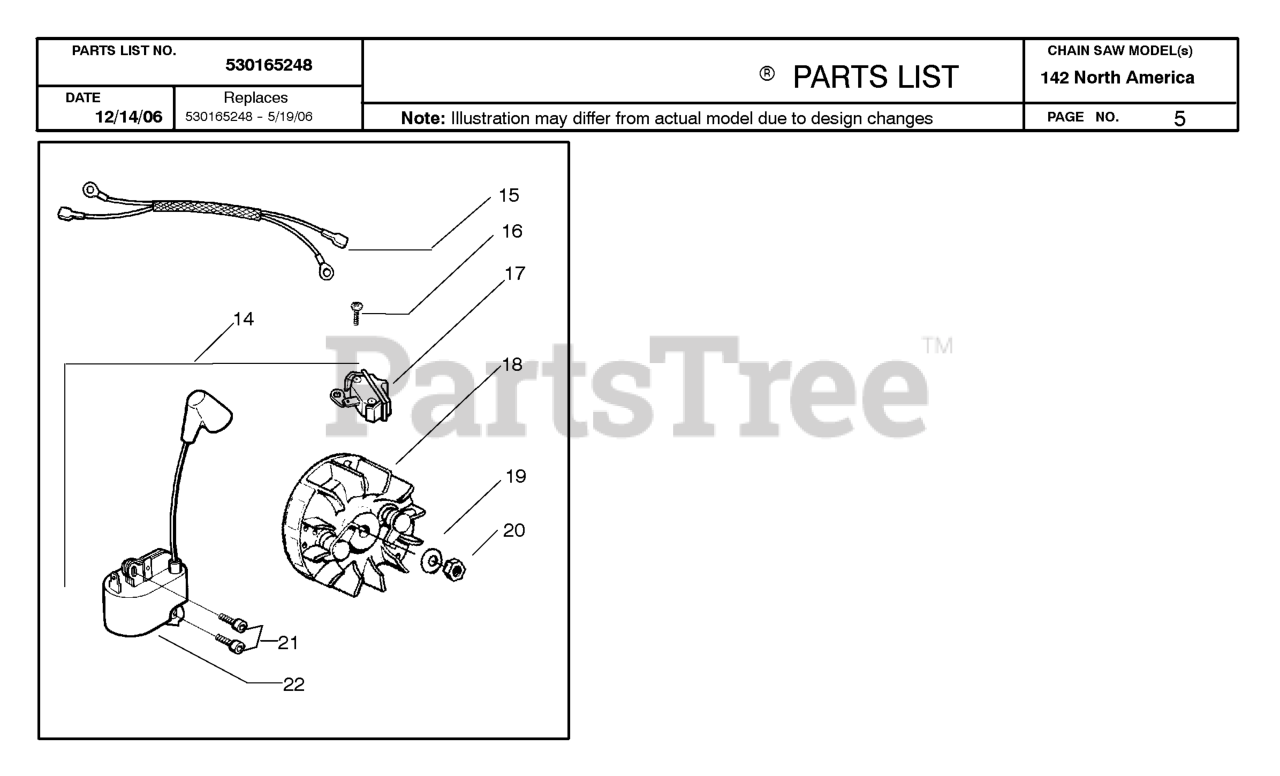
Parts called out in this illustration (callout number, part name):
14	KIT EPS IGNITION
15	LEAD WIRE ASSY
17	SWITCH ON/OFF
18	FLYWHEEL ASSY
19	WASHER-FLYWHEEL
20	NUT-FLYWHEEL
22	IGNITION MODULE
